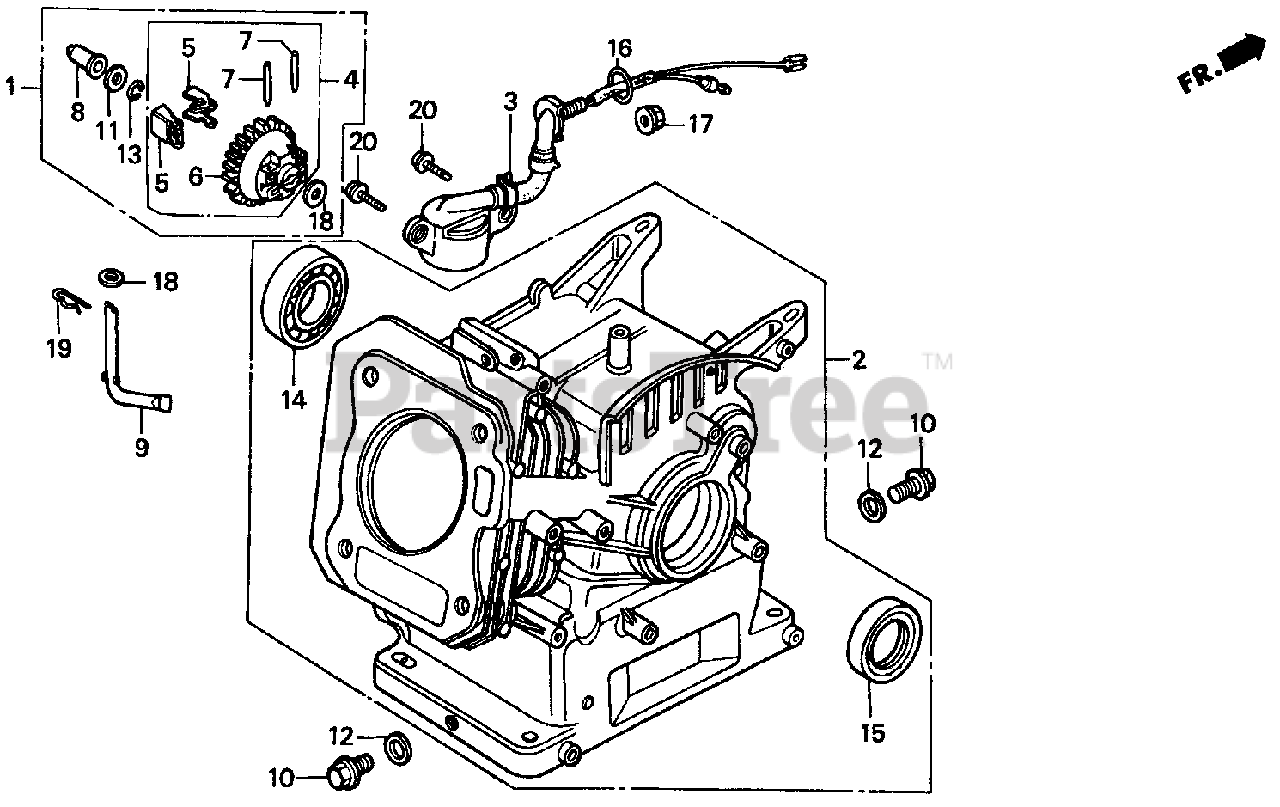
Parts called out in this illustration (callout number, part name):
1	GOVERNOR KIT
2	CYLINDER ASSY. (811)
3	SWITCH ASSY., OIL LEVEL
4	GOVERNOR ASSY.
5	WEIGHT, GOVERNOR
6	HOLDER, GOVERNOR WEIGHT
7	PIN, GOVERNOR WEIGHT
8	SLIDER, GOVERNOR
9	SHAFT, GOVERNOR ARM
10	BOLT, DRAIN PLUG
11	WASHER, THRUST (6MM)
12	WASHER, DRAIN PLUG (10.2MM)
13	CLIP, GOVERNOR HOLDER
14	BEARING, RADIAL BALL (6205)
15	OIL SEAL (25X41X6)
16	O-RING (13.5X1.5) (ARAI)
17	NUT, FLANGE (10MM)
18	WASHER, PLAIN (6MM)
19	PIN, LOCK (8MM)
20	BOLT, FLANGE (6X12)
